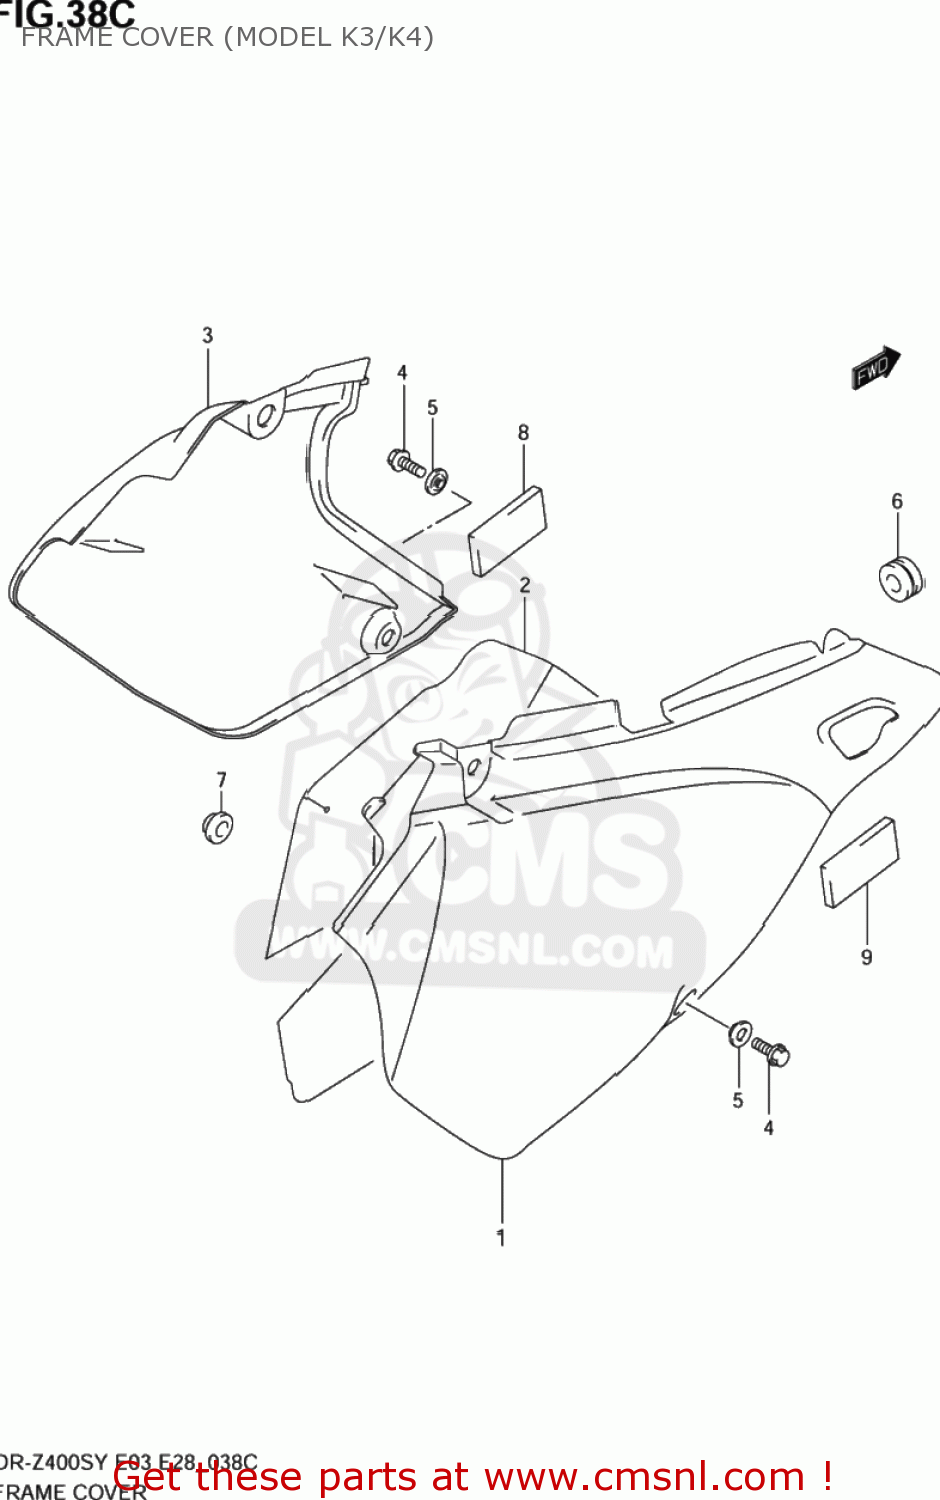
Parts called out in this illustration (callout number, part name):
1	COVER,FRAME,RIGHT (WHITE)
2	SHIELD,FRAME COVER,R
3	COVER,FRAME,LEFT
4	BOLT
5	WASHER
6	CUSHION
7	CUSHION
8	CUSHION,FRAME COVER,L
9	CUSHION
